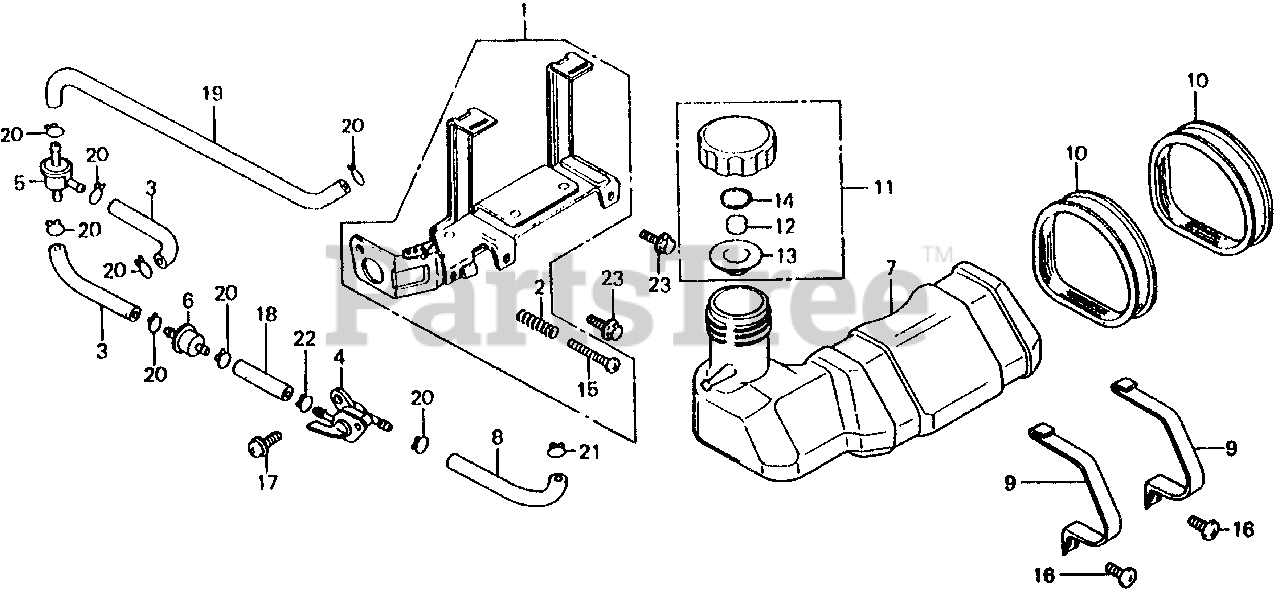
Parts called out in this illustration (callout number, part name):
1	STAY ASSY., TANK
2	SPRING, CONTROL ADJUSTING
3	TUBE, SPECIAL FUEL
4	PETCOCK ASSY.
5	FILTER, FUEL THREE-WAY
6	FILTER, FUEL
7	TANK, FUEL (NOT AVAILABLE)
8	TUBE, FUEL (NOT AVAILABLE)
9	BAND, TANK MOUNTING (NOT AVAILABLE)
10	RUBBER, TANK MOUNTING
11	CAP, FUEL TANK
12	SPONGE, FUEL CAP BREATHER
13	GASKET, FUEL CAP
14	SEPARATOR, FUEL CAP
15	SCREW, PAN (5X28)
16	SCREW, PAN (6X12)
17	SCREW-WASHER (5X12)
18	BULK HOSE, FUEL (4.5X3000) (4.5X50)
19	BULK HOSE, FUEL (4.5X3000) (4.5X330)
20	CLIP, TUBE (B8)
21	CLIP, TUBE (B10)
22	CLIP, TUBE (C9)
23	BOLT, FLANGE (8X16)
